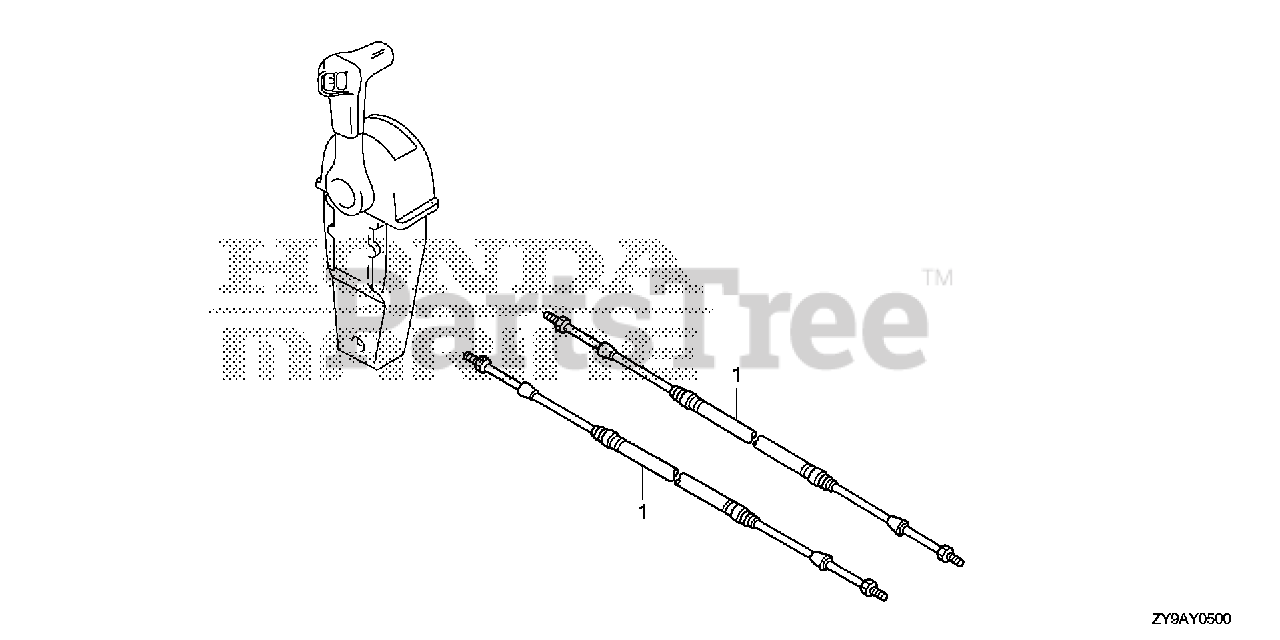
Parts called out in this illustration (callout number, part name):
1	CABLE ASSY., PUSH-PULL (33HPC-8FT)
1	CABLE, REMOTE CONTROL (10'') (LOW FRICTION)
1	CABLE ASSY., PUSH-PULL (33C-5FT)
1	CABLE, REMOTE CONTROL (11'') (LOW FRICTION)
1	CABLE ASSY., PUSH-PULL (33C-6FT)
1	CABLE, REMOTE CONTROL (12'') (LOW FRICTION)
1	CABLE ASSY., PUSH-PULL (33C-7FT)
1	CABLE, REMOTE CONTROL (13'') (LOW FRICTION)
1	CABLE ASSY., PUSH-PULL (33C-8FT)
1	CABLE, REMOTE CONTROL (14'') (LOW FRICTION)
1	CABLE ASSY., PUSH-PULL (33C-9F T)
1	CABLE, REMOTE CONTROL (15'') (LOW FRICTION)
1	CABLE ASSY., PUSH-PULL (33C-10FT)
1	CABLE, REMOTE CONTROL (16'') (LOW FRICTION) (NOT AVAILABLE)
1	CABLE ASSY., PUSH-PULL (33HPC-16FT)
1	CABLE ASSY., PUSH-PULL (33C-11FT)
1	CABLE, REMOTE CONTROL (17'') (LOW FRICTION)
1	CABLE ASSY., PUSH-PULL (33C-12 FT)
1	CABLE, REMOTE CONTROL (18') (LOW FRICTION) (NOT AVAILABLE)
1	CABLE ASSY., PUSH-PULL (33C-13 FT)
1	CABLE, REMOTE CONTROL (1 9'') (LOW FRICTION)
1	CABLE ASSY., PUSH-PULL (33C-14FT)
1	CABLE, REMOTE CONTROL (20'') (LOW FRICTION) (NOT AVAILABLE)
1	CABLE ASSY., PUSH-PULL (33HPC-20FT)
1	CABLE ASSY., PUSH-PULL (33C-15 FT)
1	CABLE, REMOTE CONTROL (21') (LOW FRICTION)
1	CABLE ASSY., PUSH-PULL (33C-16FT)
1	CABLE, REMOTE CONTROL (22') (LOW FRICTION) (NOT AVAILABLE)
1	CABLE ASSY., PUSH-PULL (33HPC-22FT)
1	CABLE ASSY., PUSH-PULL (33C-17 FT)
1	CABLE, REMOTE CONTROL (2 3'') (LOW FRICTION)
1	CABLE ASSY., PUSH-PULL (33C-18 FT)
1	CABLE, REMOTE CONTROL (24') (LOW FRICTION) (NOT AVAILABLE)
1	CABLE ASSY., PUSH-PULL (33C-19FT)
1	CABLE, REMOTE CONTROL (25') (LOW FRICTION)
1	CABLE ASSY., PUSH-PULL (33HPC-25FT)
1	CABLE ASSY., PUSH-PULL (33C-20FT)
1	CABLE, REMOTE CONTROL (26') (LOW FRICTION)
1	CABLE ASSY., PUSH-PULL (33C-21FT)
1	CABLE, REMOTE CONTROL (27') (LOW FRICTION)
1	CABLE ASSY., PUSH-PULL (33C-22FT)
1	CABLE, REMOTE CONTROL (28') (LOW FRICTION) (NOT AVAILABLE)
1	CABLE ASSY., PUSH-PULL (33C-23FT)
1	CABLE, REMOTE CONTROL (2 9') (LOW FRICTION)
1	CABLE ASSY., PUSH-PULL (33C-24FT)
1	CABLE, REMOTE CONTROL (30') (LOW FRICTION) (NOT AVAILABLE)
1	CABLE ASSY., PUSH-PULL (33C-25FT)
1	CABLE, REMOTE CONTROL (31') (LOW FRICTION)
1	CABLE ASSY., PUSH-PULL (33C-26FT)
1	CABLE, REMOTE CONTROL (32') (LOW FRICTION) (NOT AVAILABLE)
1	CABLE ASSY., PUSH-PULL (33C-27FT)
1	CABLE, REMOTE CONTROL (33') (LOW FRICTION)
1	CABLE ASSY., PUSH-PULL (33C-28FT)
1	CABLE, REMOTE CONTROL (34') (LOW FRICTION)
1	CABLE ASSY., PUSH-PULL (33C-29FT)
1	CABLE, REMOTE CONTROL (35') (LOW FRICTION)
1	CABLE ASSY., PUSH-PULL (33C-30FT)
1	CABLE ASSY., PUSH-PULL (33C-31FT)
1	CABLE ASSY., PUSH-PULL (33C-32FT)
